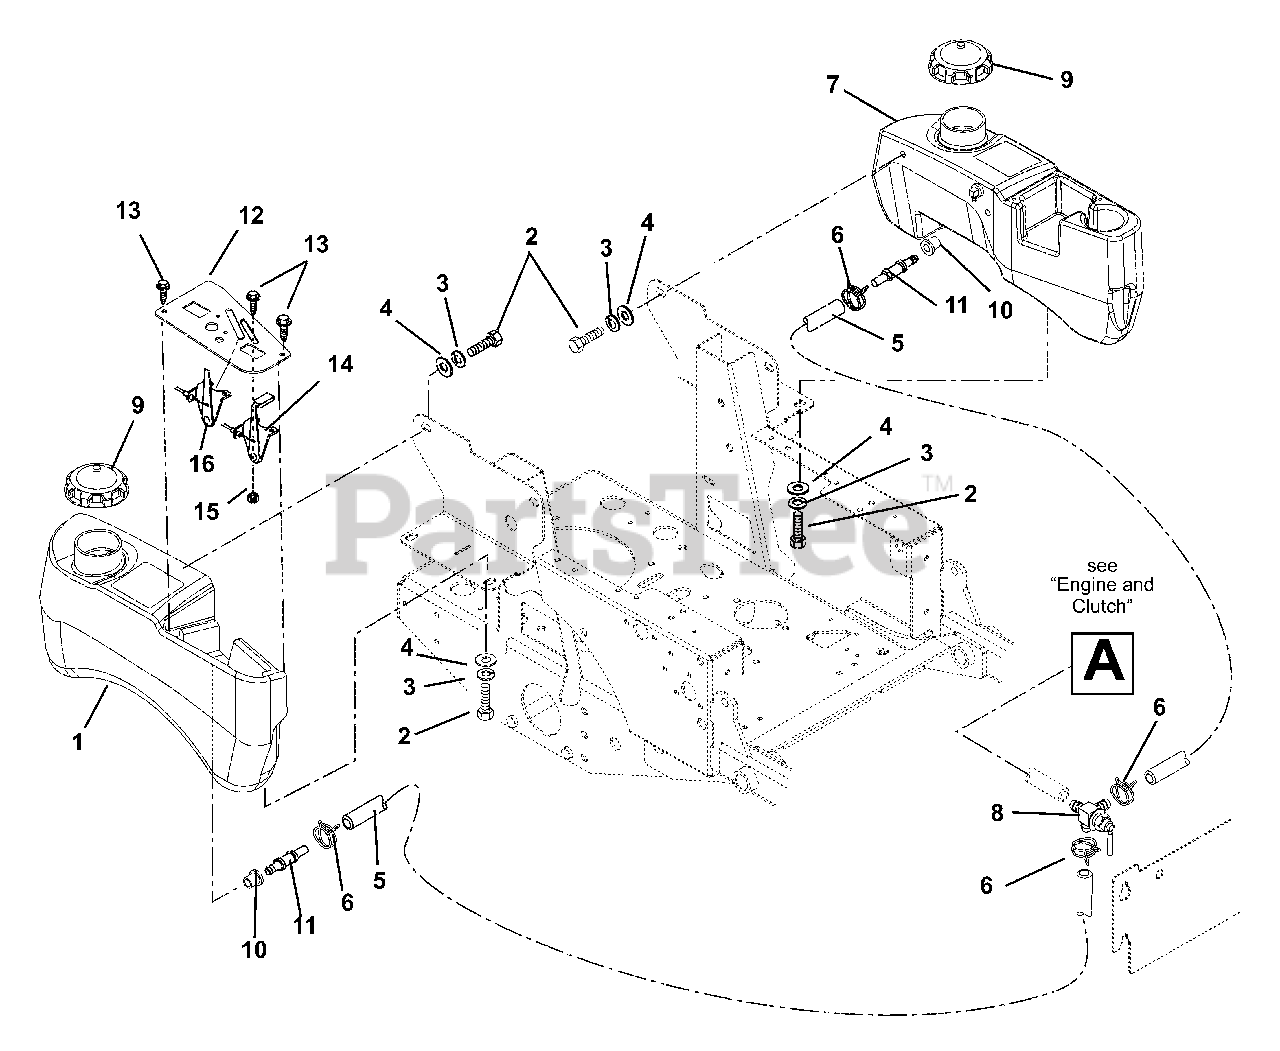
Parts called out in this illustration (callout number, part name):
1	Tank, Gas- Right Hand
2	Bolt, Hex .31-18 x .75 Grade 5
3	Washer, Locking .31 x .078
4	Washer, Flat Steel .38 x .875 x .083
5	Gas Line, Bulk .25" ID x 35"
6	Hose, Clamp
7	Tank, Left Hand Fuel (Eye-Q)
8	Valve, Fuel
9	Cap, Fuel
10	Bushing
11	Fuel Tank Fitting
12	Panel, Control
13	Screw, Machine 10-24 x .50 Hex Washer Head
14	Cable, Throttle Choke
15	Nut, Locking Nylon 10-24 With Insert
16	Cable, Choke
